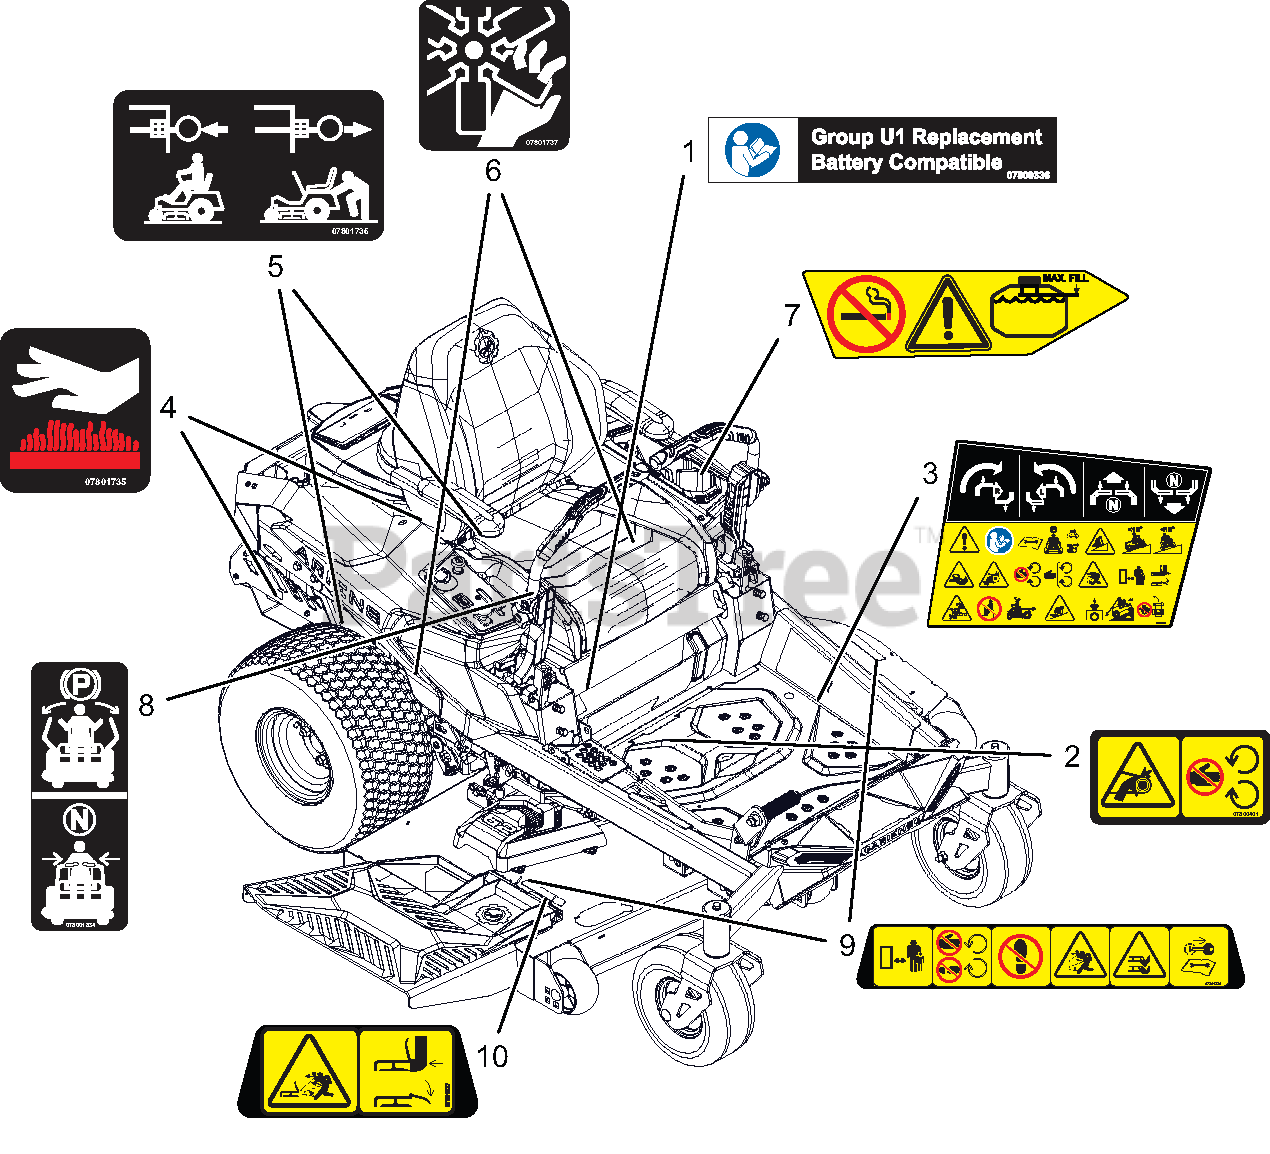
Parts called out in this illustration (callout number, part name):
1	DECAL, U1 BATTERY REPLACEMENT
2	DECAL, SAFETY - GUARDING
3	DECAL- MAIN SAFETY-INSTRUCTION
4	DECAL- HOT SURFACE
5	DECAL- TRANSAXLE DISCONNECT
6	DECAL- DANGER FAN
7	DECAL- FUEL WARNING
8	DECAL- STEERING-BRAKE
9	DECAL- SAFETY - MOWER DECK
10	DECAL- SAFETY - DECK GUARDING
